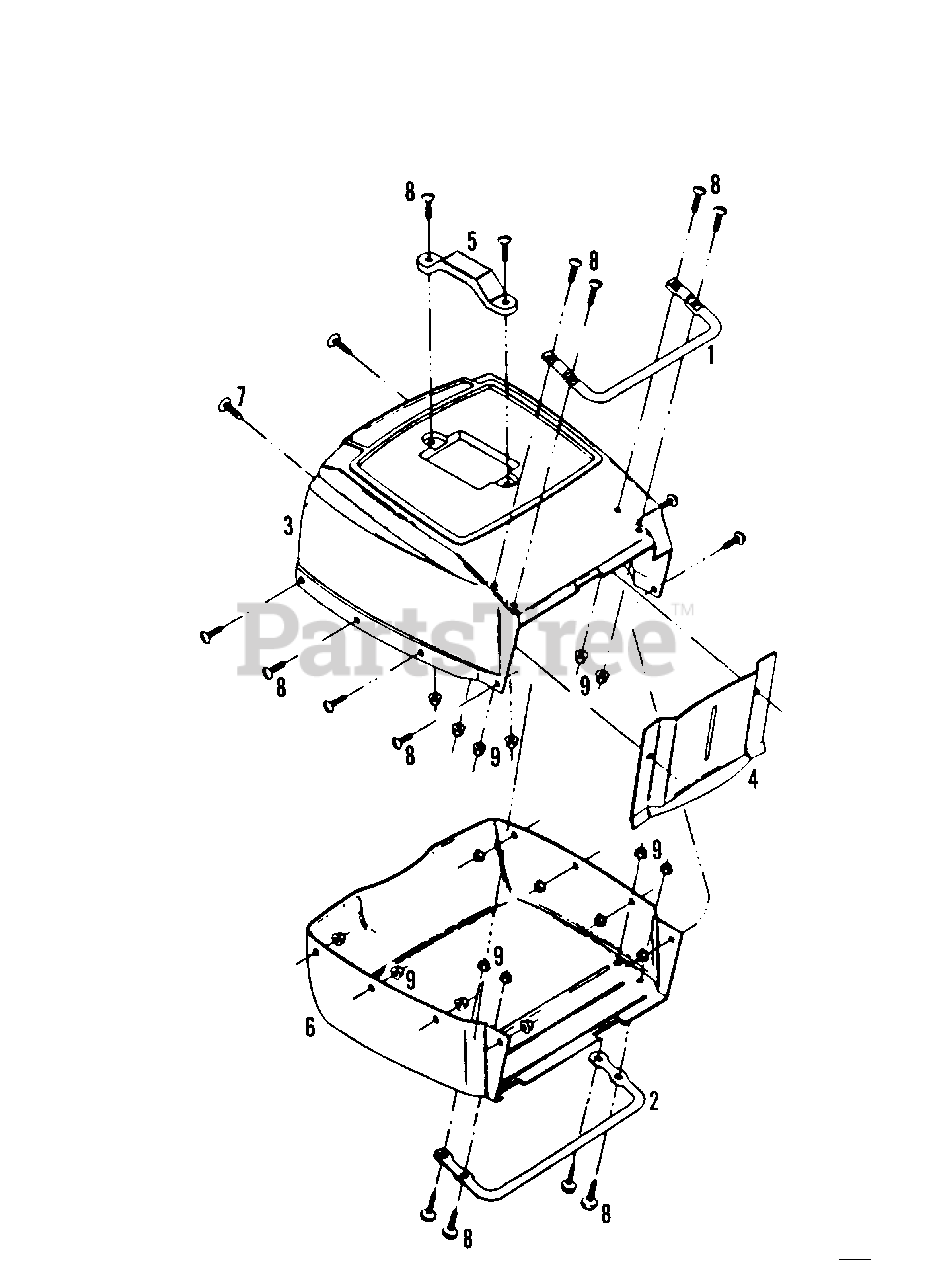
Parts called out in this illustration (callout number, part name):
1	Frame-Upper
2	Frame-Lower
3	Top-Catcher
4	Baffle-Catcher
5	Handle-Catcher
6	Bottom-Catcher
7	Fastener-Plastic
8	Screw-Slotted 1/4-20 x 5/8
9	Nut-Hex 1/4-20 Lock
